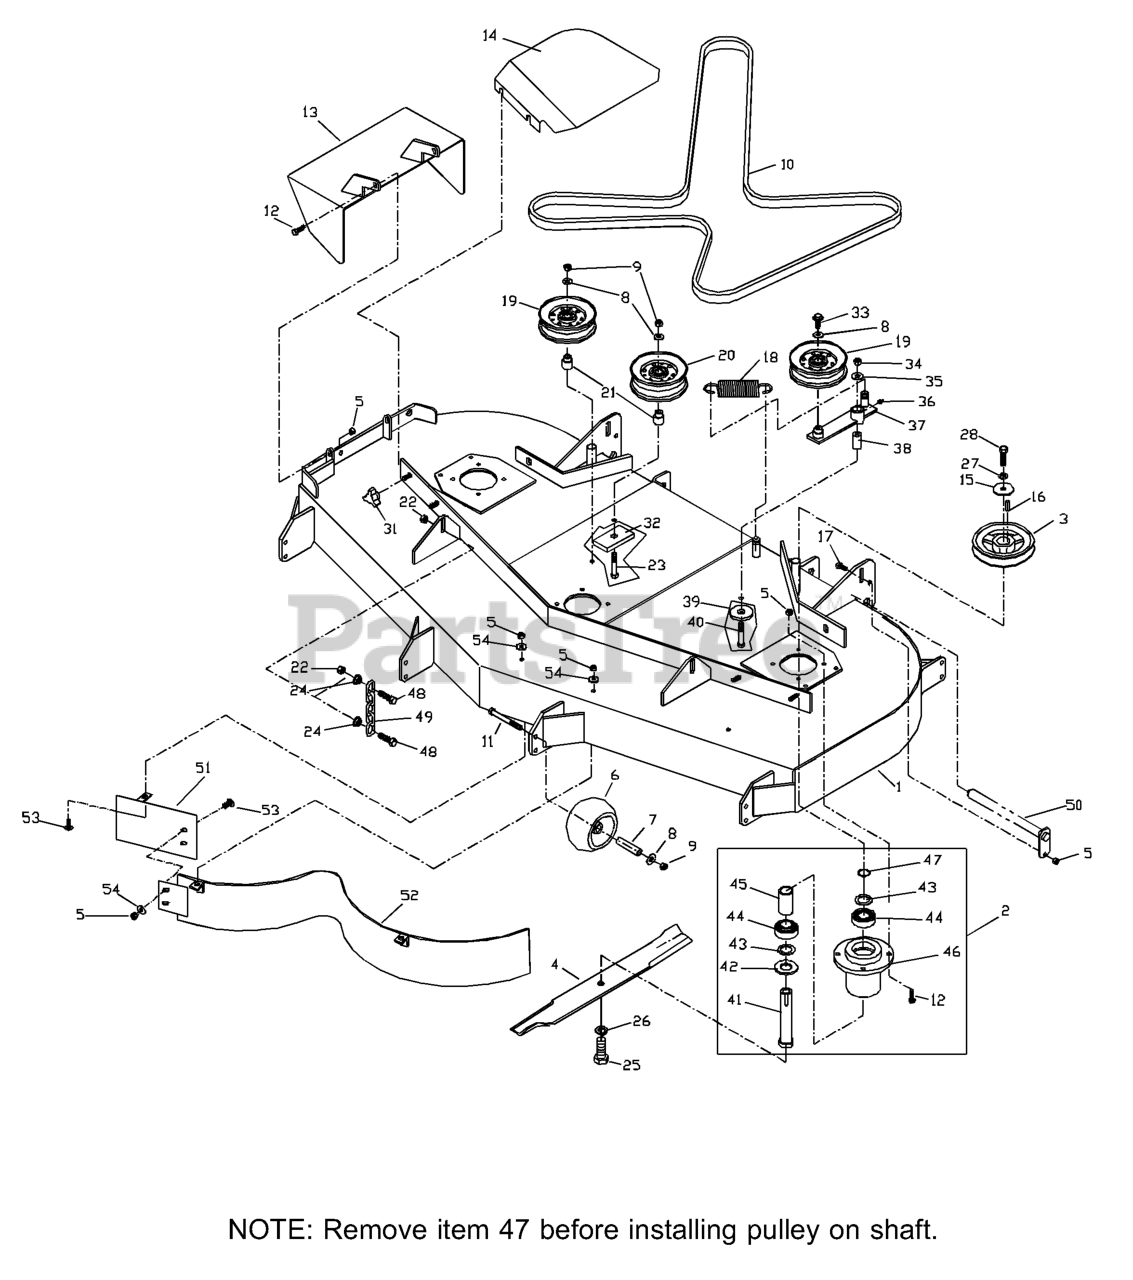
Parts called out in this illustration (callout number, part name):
1	DECK W/DECALS 52" HUS WSL
2	HOUSING ASM.
3	PULLEY 52" DECK
4	BLADE OEM 18"
5	NUT 5/16C CENTERLOCK
6	ANTI-SCALP ROLLER
8	WASHER 3/8 FLAT
9	NUT 3/8C CENTERBLOCK
10	BELT, DECK
11	HCS 3/8C X 3 1/2
12	HCS 5/16C X 1
13	DISCHARGE CHUTE
14	52 B.S.PAINTED,RT
14	52 B.S.PAINTED, LT
15	SPINDLE WASHER
16	KEY 1/4 SQ X 1 1/8
17	HCS 5/16C X 3/4
18	DECK SPRING
19	IDLER PULLEY
20	IDLER PULLEY (TALL)
21	IDLER BUSHING
22	NUT 7/16C CENTERLOCK
23	HCS 3/8C X 2 1/2
24	NUT 7/16C WHIZ
25	HCS 5/8F X 1 1/4
26	LOCKWASHER 5/8
27	WASHER 7/16 LOCK
28	HCS 7/16F X 1 1/2
31	KNOB, THREE PRONG
32	SUPPORT PLATE
33	4CS 3/8C X 1 SERRATED HEAD
34	NUT 1/2-13 HEX NYLOC ZD
35	WASHER 1/2 FLAT
36	ZERK
38	PIVOT BUSHING
39	WASHER, SUPPORT
40	HCS 1/2C X 3 1/4
42	MACHINERY BUSHING 10 GA.
43	BUSHING.MACHINE.18.GAUGE
44	BEARING
46	HOUSING, DIE CAST
48	HCS 7/16C X 1 1/2
49	LIFT CHAIN
51	CENTER BAFFLE - 52"
52	MAIN BAFFLE 52"
53	CARRIAGE BOLT 5/16C X 5/8"
54	WASHER 5/16 FLAT
